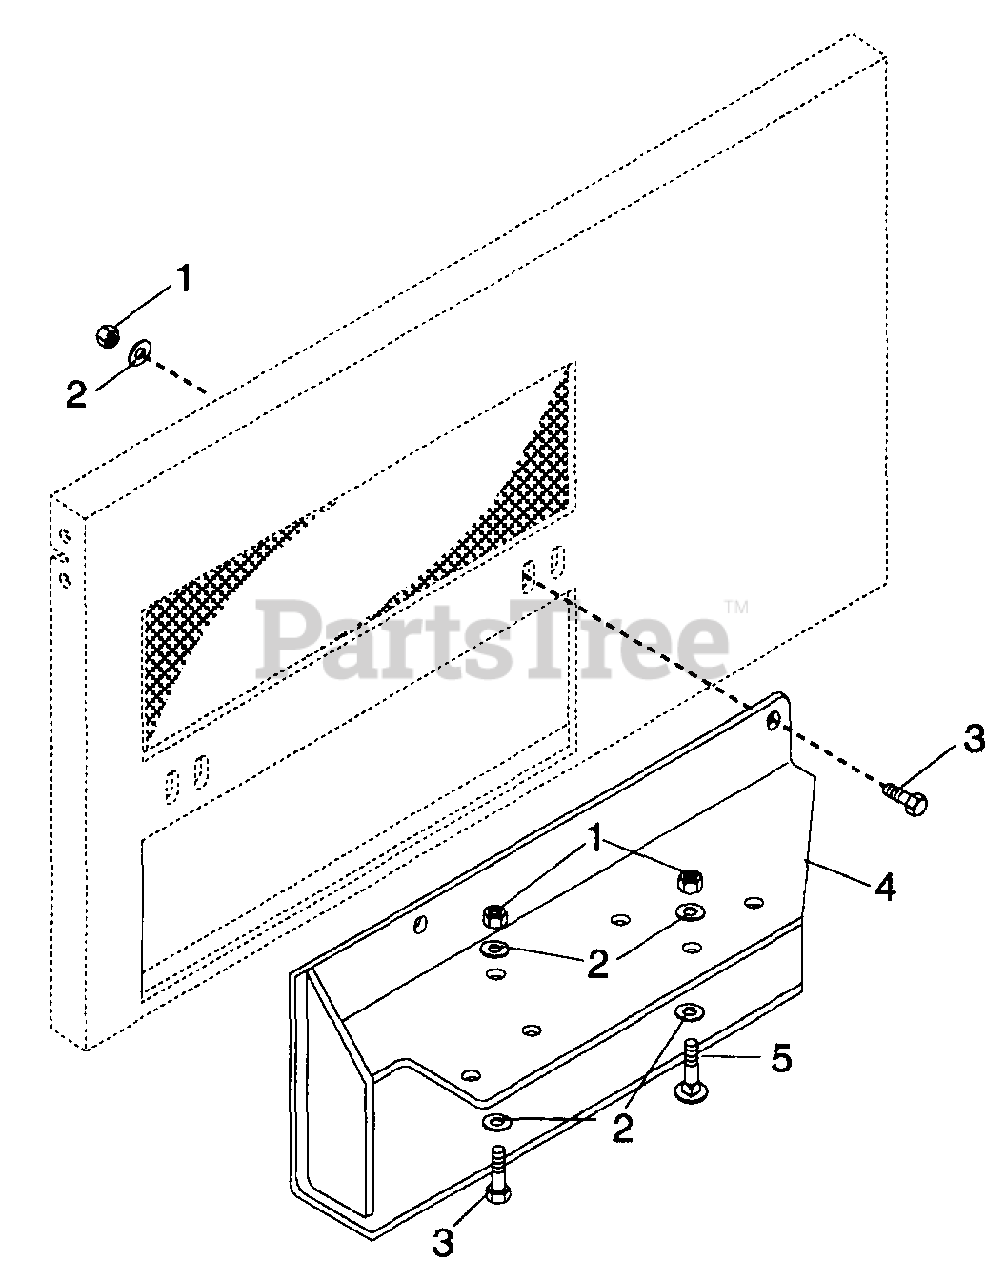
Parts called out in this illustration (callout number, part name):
1	Nut-Locking-Nylon .375-16 Grade 2
2	Washer-Flat-Steel .406 x .812 x .065
3	Bolt-Hex .38-16 x 1.00 Grade 5
4	Weldment, Chute Adapter
5	Bolt-Round Head Square Neck .38-16 x 1.0
